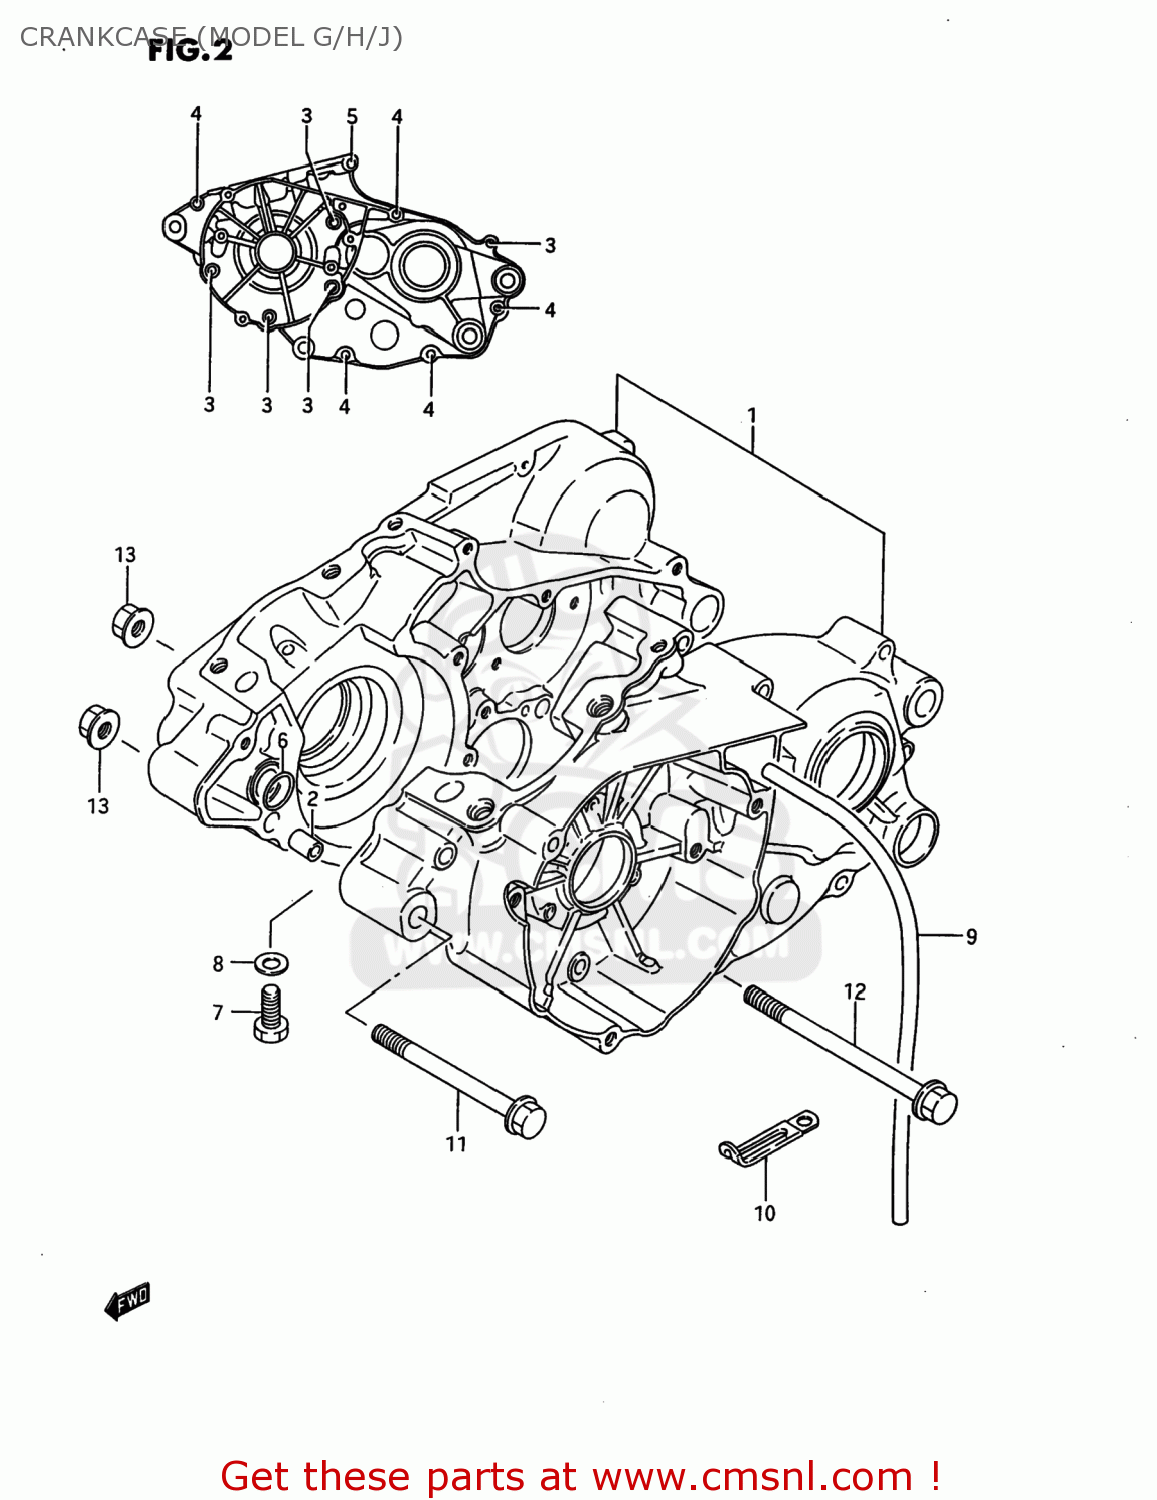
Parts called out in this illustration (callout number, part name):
1	CRANKCASE SET
2	PIN
3	SCREW
4	SCREW
5	SCREW
6	O RING(D:1.9,ID:13.8)
7	BOLT,8X16
8	GASKET 8.2X14X1 (NAS)
9	HOSE(4X7X600)
10	CLAMP
11	BOLT(8X95)
12	BOLT 8X105
13	NUT
